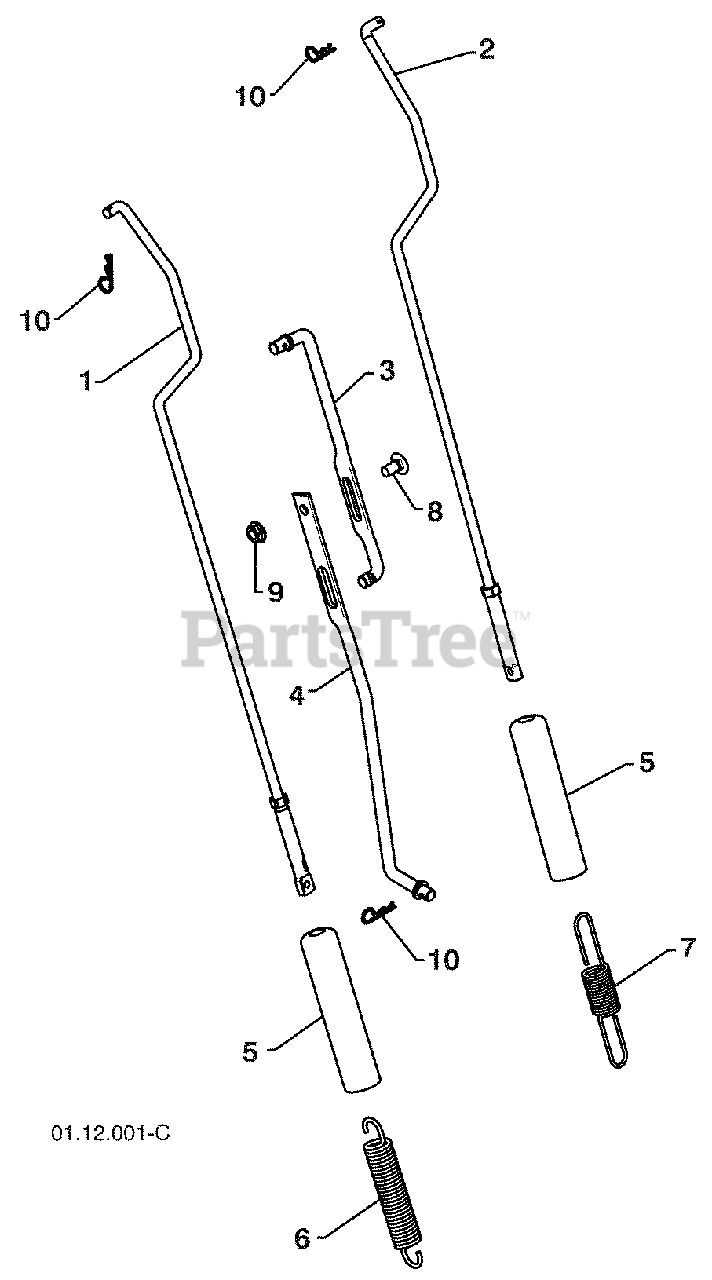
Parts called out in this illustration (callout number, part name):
1	IMPELLER ROD
2	TRACTION ROD
3	SHIFTER ROD TOP
4	SHIFTER ROD BOTTOM
5	SPRING SLEEVE
6	IMPELLER SPRING
7	TRACTION SPRING
8	CARRIAGE BOLT 5/16-18 X .75
9	NUT 5/16-18
